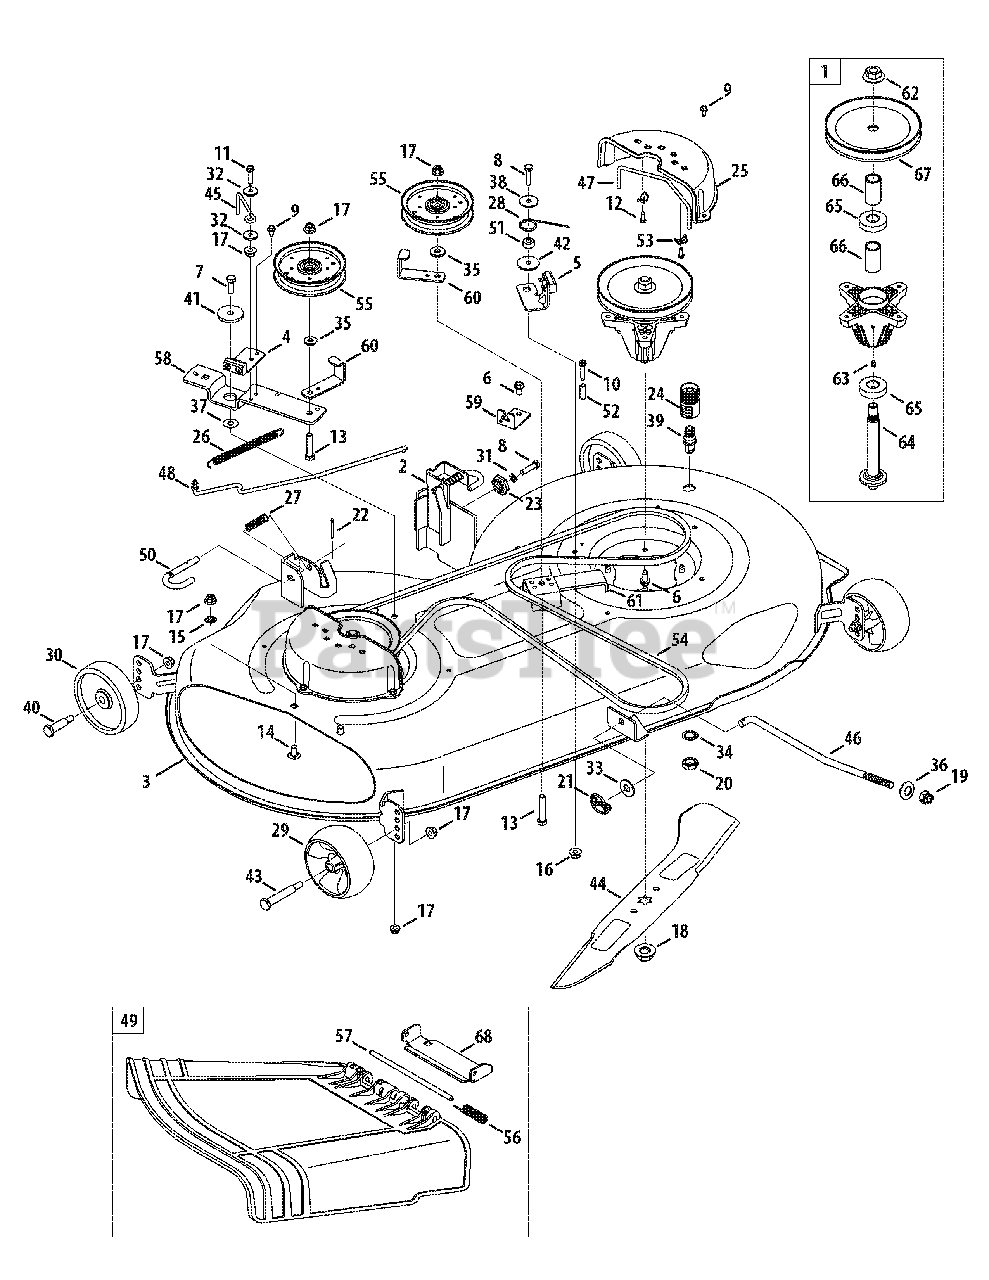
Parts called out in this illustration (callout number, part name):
1	Spindle Assembly, Pul 6.93 Dia
2	Bracket Assembly, Deck Hanger, LH
3	Deck Assembly, Offset, 46"
4	Brake Assembly, Deck, 42/46
5	Brake Assembly, Deck, 46"
6	Screw, Self-tapping, 5/16-18, .750,
7	Hex Screw, 3/8-16, 1.00, Gr5, Std
8	Hex Screw, 5/16-18, 1.25, Gr5, Std
9	Screw, Self-tapping, 1/4-20, 0.500
10	Screw, Self-tapping, 1/4-20, 1.500
11	Screw, Self-tapping, 1/4-20, 1.250
12	Screw, B, #10-16, 0.625
13	Hex Screw, 3/8-16, 2.00, Gr5, Std
14	Bolt, Carriage, 3/8-16, 0.75, Gr1
15	Nut, Push, 3/8
16	Nut, Flange Lock, 5/16-18, Nylon
17	Nut, Flange Lock, 3/8-16, Nylon
18	Nut, Flange, 5/8-18
19	Nut, Lock, 1/2-13
20	Nut, Hex, M16-1.5
21	Pin, Lynch, .1875
22	Pin, Cotter, 1/8 x 1.25
23	Gear, Deck Adjustment
24	Adapter, Water Port
25	Belt Cover, Universal
26	Spring, Extension, .62 x 6.12
27	Spring, Compression, .535 x 1.751
28	Spring, Torsion, .992 ID x 1.17 OD
29	Wheel, Deck, 5.0 Dia Ball
30	Wheel, Deck 5.0 x 1.38
31	Washer, Lock, 5/16, Regular Duty
32	Washer, Flat, .265 x .938 x .120
33	Washer, Flat, .531 x 1.25 x .100
34	Washer, Lock, 5/8, Int Tooth
35	Washer, Flat, .385 x .870 x .092
36	Washer, Bell, .63 x 1.25 x .18
37	Washer, Flat, .385 x 1.0 x .030
38	Washer, Flat, .330 x 1.25 x .06, Ht
39	Deck Port, Water
40	Bolt, Shoulder, .496 x 1.525, 3/8-16
41	Spacer, Shoulder, .8840 x .190
42	Spacer, Shoulder, .5000 x .1475
43	Bolt, Shoulder, .496 x 2.50, 3/8-16
44	Blade, Cut, 23.25" 2-In-1, Cub
45	Rod, Belt Keepr, 42 Idler
46	Rod, Lift, Deck, Frt, 13.7
47	Rod, Keeper, Belt
48	Rod, Control, Brake 46"
49	Chute Assembly, 46" Offset Cub
50	Rod, Deck Release
51	Spacer, .315 x .750 x .375
52	Spacer, .260 x .375 x 1.030
53	Clamp, Casing
54	Belt, V-Type, A-Sec
55	Pulley, Idler, 4.25"Dia
56	Spring, Torsion, .44 I.D. x 2.0
57	Pin, Hinge, 7.96
58	Bracket, Idler, Pivot, 46
59	Bracket, Cable, Deck Engagement
60	Bracket, Guard, Belt, 4.25 Pulley
61	Bracket, Support, Deck Idler
62	Nut, Flange, 5/8-18
63	Lube Fitting, 3/16
64	Shaft, Spindle, 6.11 Lg.
65	Bearing, Ball, .787 x 1.85 x .551
66	Spacer, .792 x 1.060 x 1.860 Lg
67	Pulley, Deck, 6.93 Dia
68	Bracket, Chute, 46
